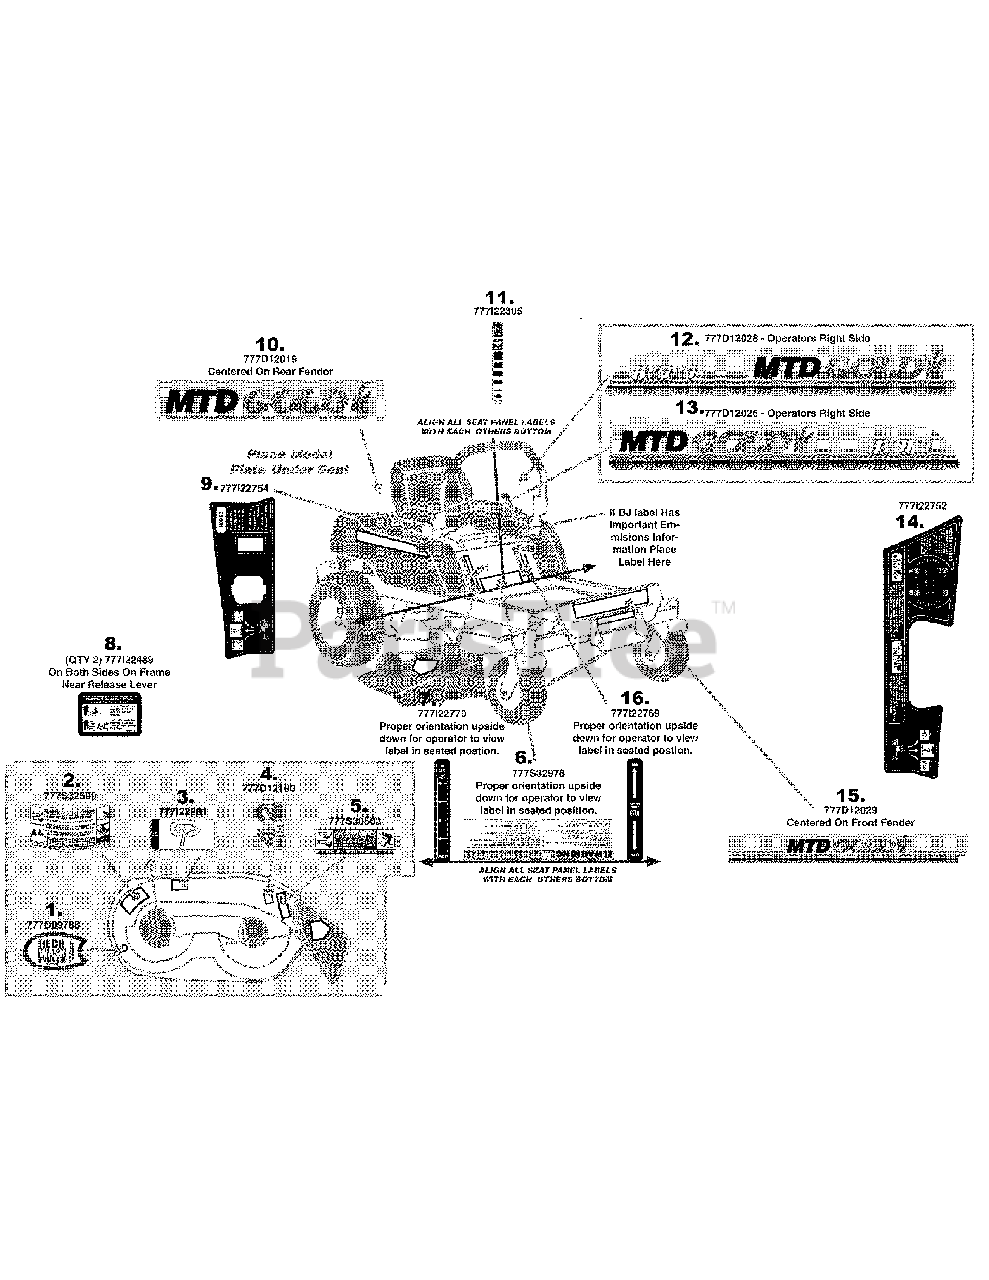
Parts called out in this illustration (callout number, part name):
1	LABEL:RIDER:WHITE
2	LABEL-RZT DECK WARNG CURVE
3	LABEL-BELT ROUTE
4	LABEL-RIDER RZT DECK 42"
5	LABEL-DANGER CHUTE
6	LABEL-COMMON WARNING
7	LABEL-HANDLE HEIGHT
8	LABEL-TRNMSN RELEASE
9	LABEL-RH CONTROL
10	LABEL-RIDER REAR FENDER MTD GOLD
11	LABEL-THROTTLE
12	LABEL-RZT POD MTD GOLD LH
13	LABEL-RZT POD MTD GOLD RH
14	LABEL-LH CONTROL
15	LABEL-RZT FRONT MTD GOLD
16	LABEL-PARK BRAKE
